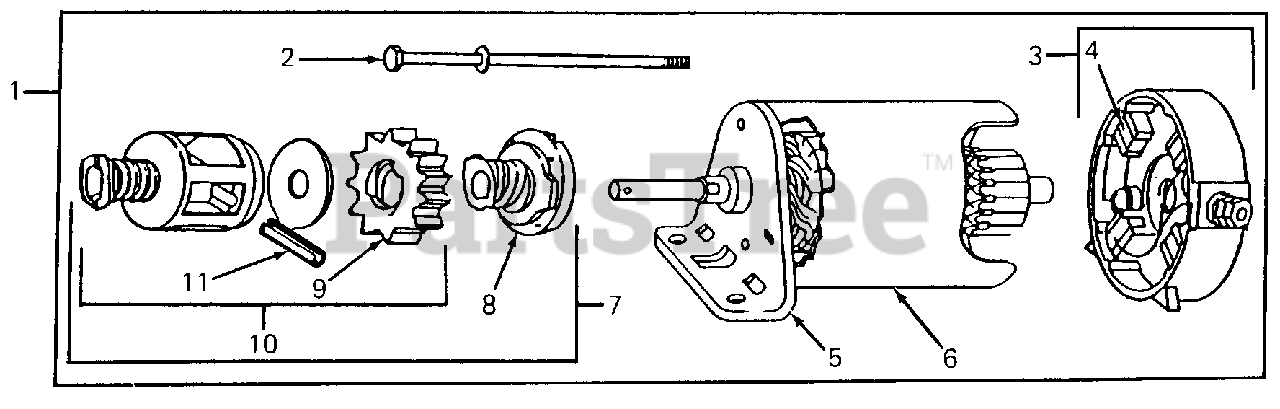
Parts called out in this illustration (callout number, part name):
1	Motor Assy, Starter
3	Cap Assy Commutator
4	Brush Assy
5	Cap, Drive End
7	Drive Assy
8	Clutch, Starter
9	Gear
10	Retainer Kit
